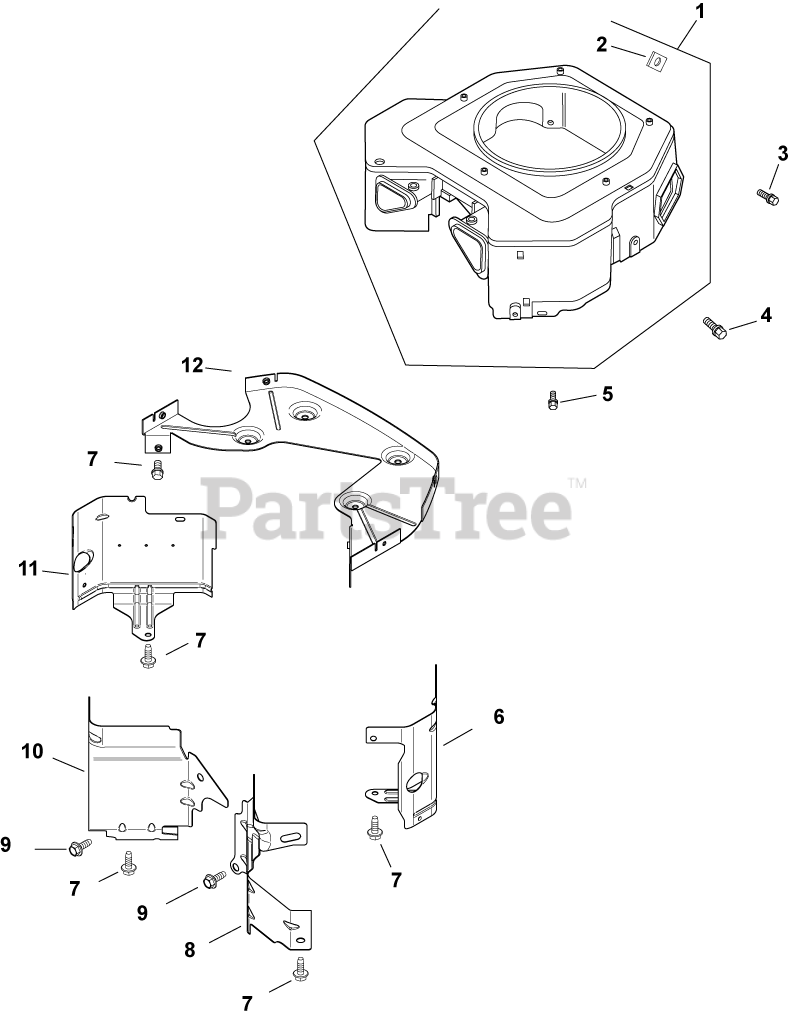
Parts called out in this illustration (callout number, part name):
1	KIT, BLOWER HOUSING USE 24 027 451-S
2	NUT, PLASTIC (KM)-USE 25 100 37-S
3	SCREW,FLG THD FRM M5X0.8X16-(#25086398S)
4	SCREW, HVY FLG M5X.8X16
5	SCREW, FLG THD FRM M5X.8X20-(#25086399S)
6	BAFFLE,VALLEY #2SIDE(KM)-USE 24 063 88-S
7	SCREW,FLG THD FRM M6X1.0X16-(#25086397S)
8	BAFFLE, VALLEY #2 SIDE-USE 24 063 94-S
9	SCREW, FLG THD FRM M5X.8X10
10	BAFFLE, VALLEY (CV)-USE 24 063 93-S
11	BAFFLE, RIGHT BARREL-USE 24 063 85-S
12	PLATE, BACKING-USE 24 146 59-S
